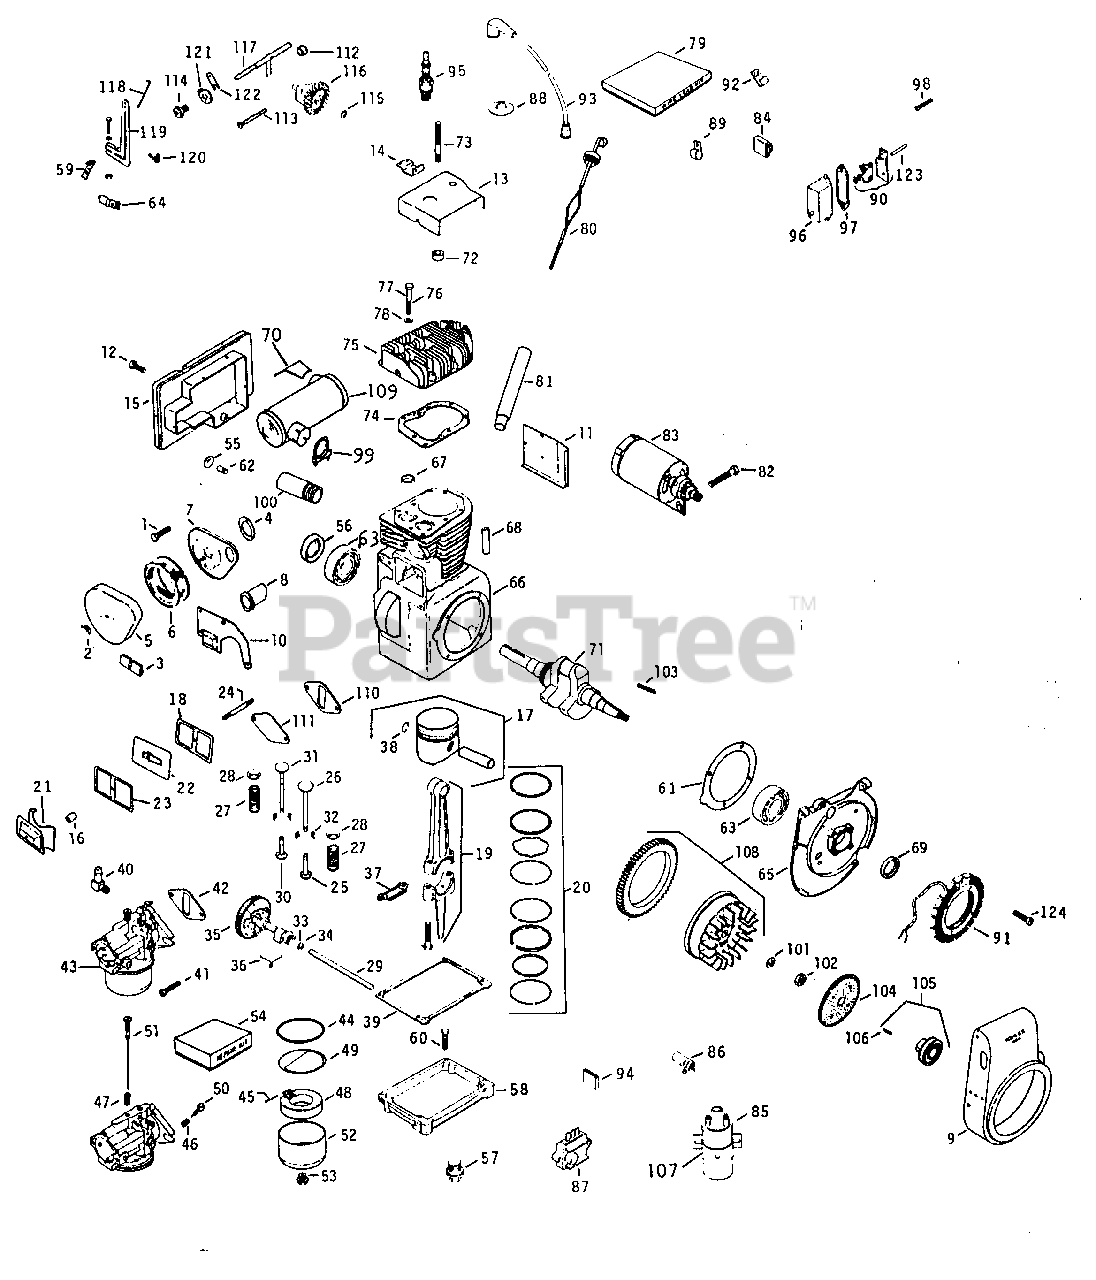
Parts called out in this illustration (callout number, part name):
1	Screw, 8-32 X 1/2 Znd Hex Hd Self Tap
2	Nut, Wing
4	Gasket, Air Cleaner
5	Cover, Air Cleaner
6	Element, Air Cleaner
7	Base, Air Cleaner
8	Tube, Air Cleaner
9	Housing, Blower
10	Baffle, Side
11	Baffle, Cylinder
12	Screw w/Lock Washer, 1/4-20 X 1/2 Znd Hex Hd Mach
13	Baffle, Head
14	Bracket, Lifting
15	Duct, Air
16	Seal, Breather
17	Piston Assy, Std
18	Gasket, Breather & Vent
19	Rod Assy, Connecting, Std
20	Ring Set, Piston, Std
21	Breather & Vent Assy
22	Plate, Breather Assy
23	Gasket, Plate
24	Stud, Breather Plate
25	Tappet, Intake
26	Valve, Intake
27	Spring, Valve
28	Retainer, Valve Spring
29	Pin, Camshaft
30	Tappet, Exhaust
31	Valve, Exhaust
32	Key, Valve Spring
33	Shim, Camshaft, .005
34	Shim, Camshaft, .010
36	Spring, Camshaft Actuating
37	Lock, Screw
38	Retainer, Piston Pin
39	Gasket, Oil Pan Base
40	Elbow, Hose Connector
41	Screw, 1/4-20 X 3/4 Znd Slt Hex Hd Mach
42	Gasket, Carburetor
43	Carburetor Assy
44	Gasket, Fuel Bowl
45	Pin, Hinge
46	Spring, Idle Adjusting Screw
47	Spring, High Speed Needle
48	Float & Lever Assy
49	Gasket, Bowl Baffle
50	Screw, Idle Adjusting
51	Needle, High Speed
52	Bowl, Fuel
53	Screw w/Gasket, Fuel Bowl
54	Kit, Carburetor Repair
55	Plug, 1-1/8 Expansion
56	Seal, Rear Oil
57	Plug, 3/8-18 Auto Sq Hd Drain
58	Base, Oil Pan
59	Bracket, Choke
60	Screw w/Lock Washer, 5/16-18 X 1-1/2 Znd Hex Hd Mach
61	Gasket, Bearing Plate
62	Shaft, Governor
63	Bearing, Crankcase Ball
64	Clip, Choke Bracket Speed
65	Plate, Crankcase Bearing
66	Block, Cylinder
67	Insert, Exhaust Valve
68	Guide, Valve
69	Seal, Front Oil
70	Deflector, Exhaust
73	Stud, Cylinder Head
74	Gasket, Cylinder Head
75	Head, Cylinder
76	Screw w/Lock Washer, 1/4-20 X 1/2 Znd Hex Hd Mach
77	Screw, 5/16-18 X 1-1/2 Znd Hex Hd Cap Type 8
78	Washer, Head
79	Kit, Coil Breaker Point Cable
80	Dipstick Assy
81	Tube, Oil Fill
82	Screw, 3/8-16 X 7/8 Znd Hex Hd Cap
83	Starter Motor Assy
85	Coil, Ignition
86	Condenser, Ignition Coil
87	Regulator Assy
88	Grommet, Spark Plug
89	Clip, Cable
90	Breaker & Bracket Assy
91	Kit, Stator
92	Clip, Terminal
93	Kit, Hi-Tension Lead
94	Connector
95	Plug, Spark (Champion)
96	Cover, Breaker
97	Gasket, Breaker Cover
98	Screw, 10-24 X 1 Znd Pan Hd Mach
99	Clamp Assy, Muffler
100	Nipple, Exhaust
102	Nut, 5/8-18 Znd Hex Lock
103	Key, 3/16 X 1-3/8 Sq Parallel
104	Screen, Grass
105	Cup Assy, Flywheel Drive
106	Pin, Flywheel Drive Cup
107	Clamp, Ignition Coil
108	Flywheel Assy
109	Muffler Assy
110	Gasket, Pump Cover
111	Cover, Pad
112	Bearing, Governor Needle
113	Pin, Governor Stop
114	Bushing, Governor Shaft
115	Washer, Thrust
116	Gear, Governor
117	Shaft, Governor
118	Linkage, Governor
119	Lever, Governor
120	Spring, Governor
121	Disc, Governor Regulating
122	Bracket, Speed Control
123	Rod, Breaker
124	Screw, 10-24 X 3/8 Fil Hd Mach
